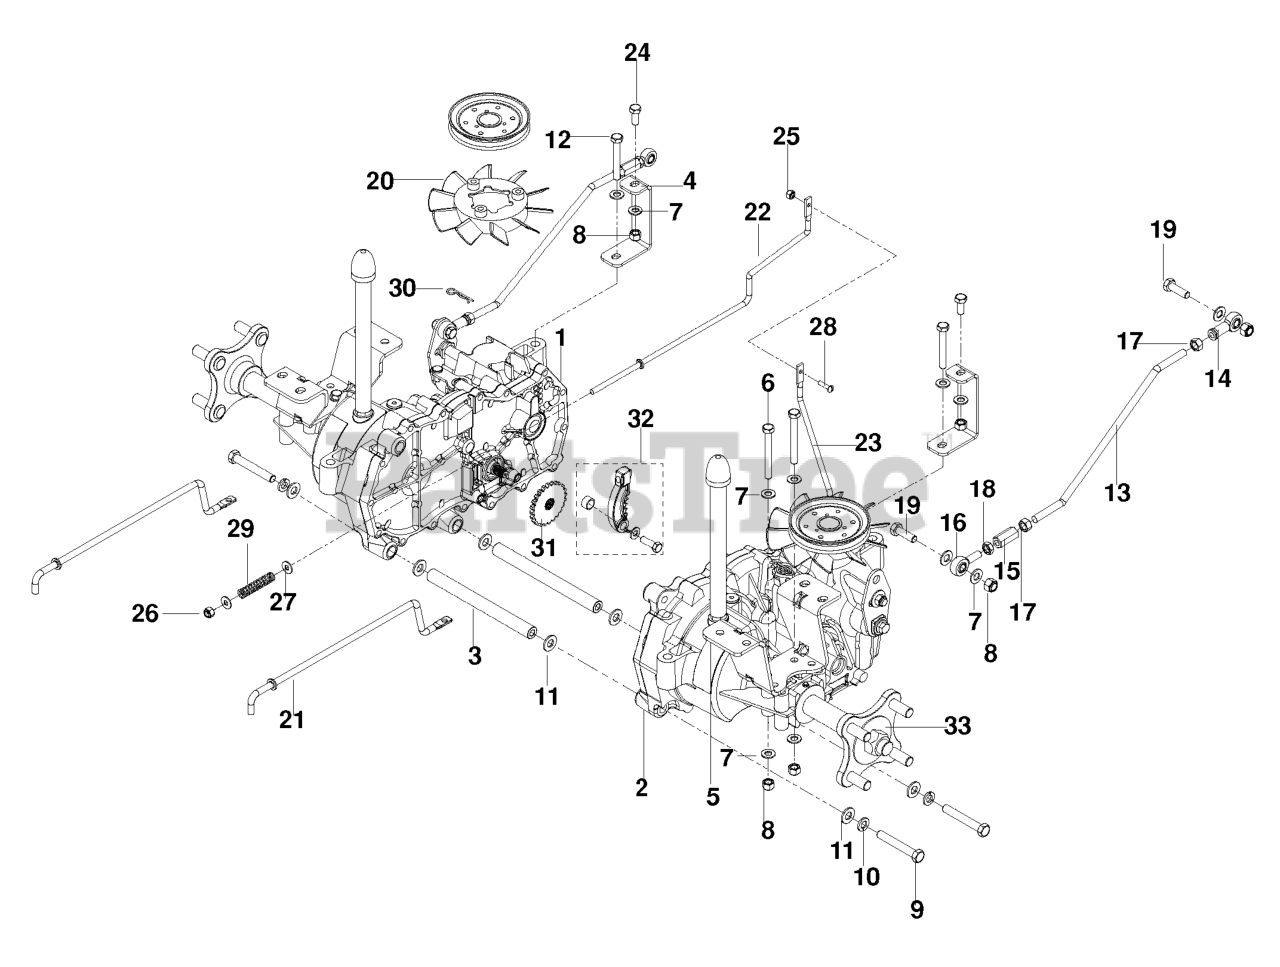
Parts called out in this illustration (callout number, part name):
1	HG_EZT, LT
2	HG_EZT, RT
3	SPACER TUBE, EZT
4	SUPPORT.FRONT.TRANS.BLACK.
5	EZT MOUNT, REAR, BLACK
6	HCS 5/16C X 2-3/4
7	FLAT WASHER 5/16 SAE
8	NUT 5/16 NYLOC
9	HCS 3/8C X 2 1/2
10	SLW 3/8 STD
11	WASHER 3/8 SAE FLAT
13	RP.ROD, MOTION CONTROL
14	RH ROD END
15	ROD END COUPLER
16	RP.ROD.END.LH
18	NUT 5/16F LEFTHAND
19	HCS 5/16C X 1
20	HG_HYDRO FAN 51365
21	LINKAGE, BYPASS, EZT
22	LINKAGE.BRAKE.LT
23	LINKAGE, BRAKE RT
24	HCS 5/16C X 3/4
25	NUT 10-24 NYLOC
26	NUT.1/4-20.HEX.NYLOC.ZD
27	WASHER 1/4 SAE
28	SCR #10-24 X 3/4
30	HAIRPIN #2
31	HG_DISC COG BRAKE 51635
32	HG_KIT BRAKE ARM (EZT)
33	HG_KIT, HYDRO-GEAR HUB
